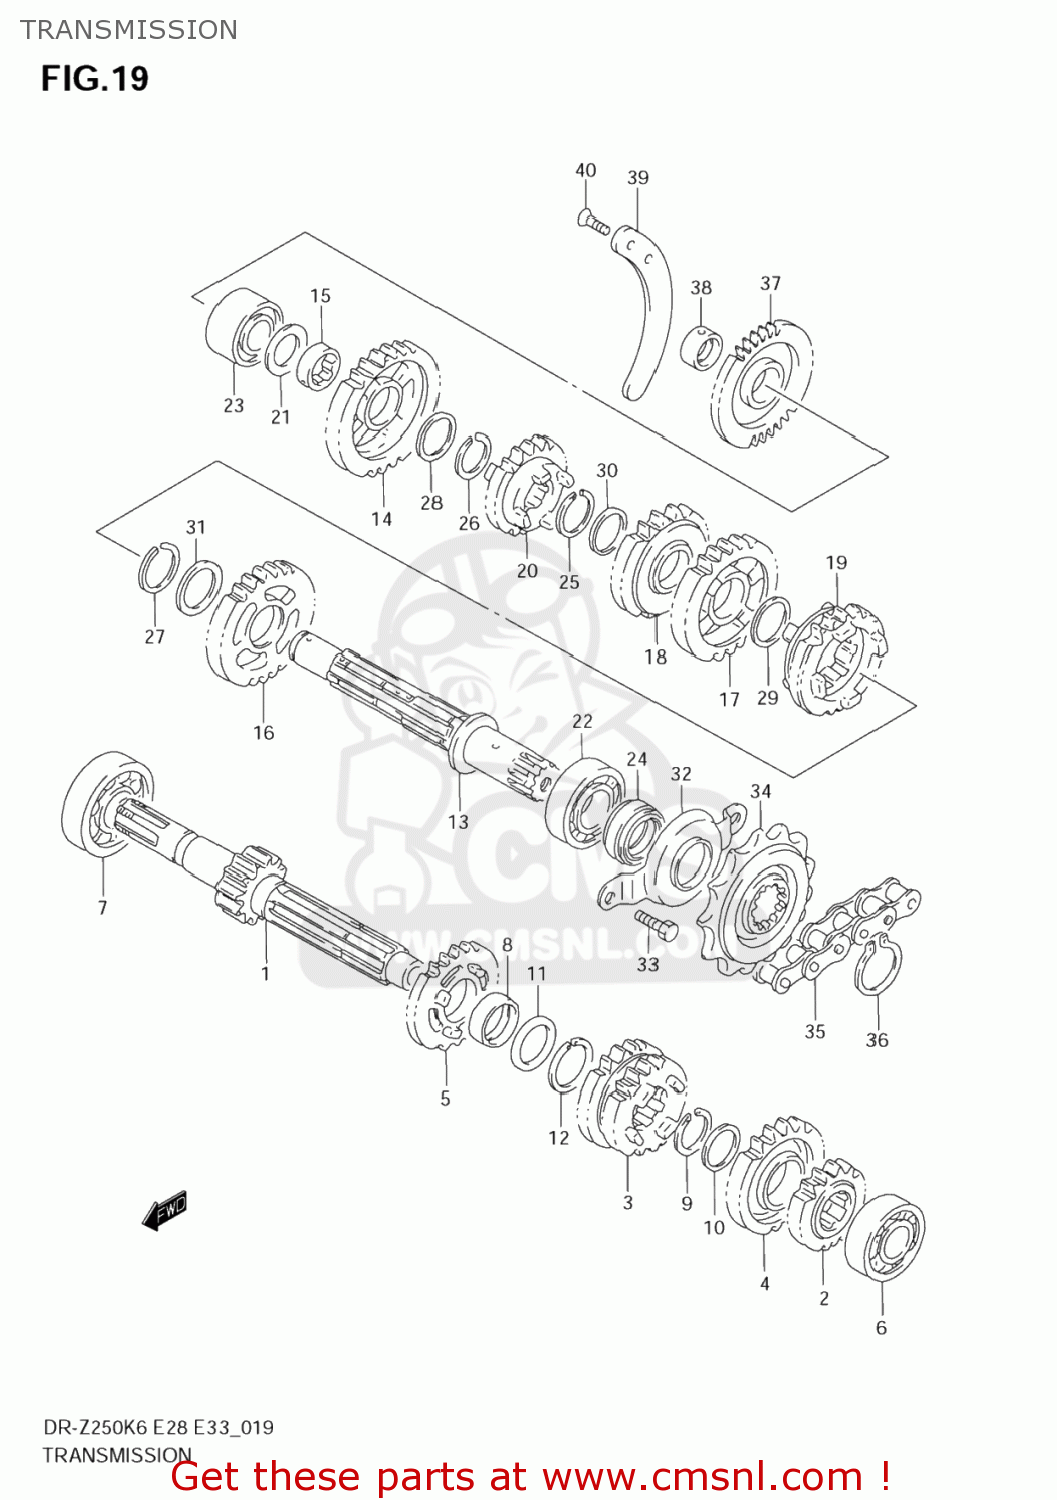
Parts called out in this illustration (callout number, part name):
1	SHAFT,COUNTER(NT:12)
2	GEAR,2ND DRIVE(NT:15)
3	GEAR,3RD & 4TH DRIVE(NT:18/18)
4	GEAR,5TH DRIVE(NT:21)
5	GEAR,6TH DRIVE(NT:23)
6	BEARING(17X40X12)
7	BEARING 20X52X15
8	BUSH(22X26X9)
9	CIRCLIP
10	SHIM(22X26X1)
11	SHIM(22X30X1)
12	CIRCLIP
13	SHAFT,DRIVE
14	GEAR,1ST DRIVEN(NT:29)
15	BUSH,1ST DRIVEN GEAR
16	GEAR,2ND DRIVEN(NT:26)
17	GEAR,3RD DRIVEN(NT:24)
18	GEAR,4TH DRIVEN(NT:20)
19	GEAR,5TH DRIVEN(NT:20)
20	GEAR,6TH DRIVEN(NT:19)
21	SHIM(22X30X1)
22	BEARING(22X56X16)
23	BEARING(17X40X17.5)
24	SEAL,OIL(22X34X7)
25	CIRCLIP
26	CIRCLIP
27	CIRCLIP
28	WASHER
29	SHIM(22X28X1)
30	SHIM(22X28X1)
31	SHIM(25X34X1)
32	RETAINER,DRIVE SHAFT OIL SEAL
33	BOLT
34	SPROCKET,ENGINE(NT:13)
35	CHAIN,DRIVE
36	CIRCLIP
37	GEAR,KICK STARTER IDLE(NT:27)
38	BUSH,KICK STARTER IDLE GEAR
39	RETAINER,KICK IDLE GEAR
40	SCREW(6X16)
